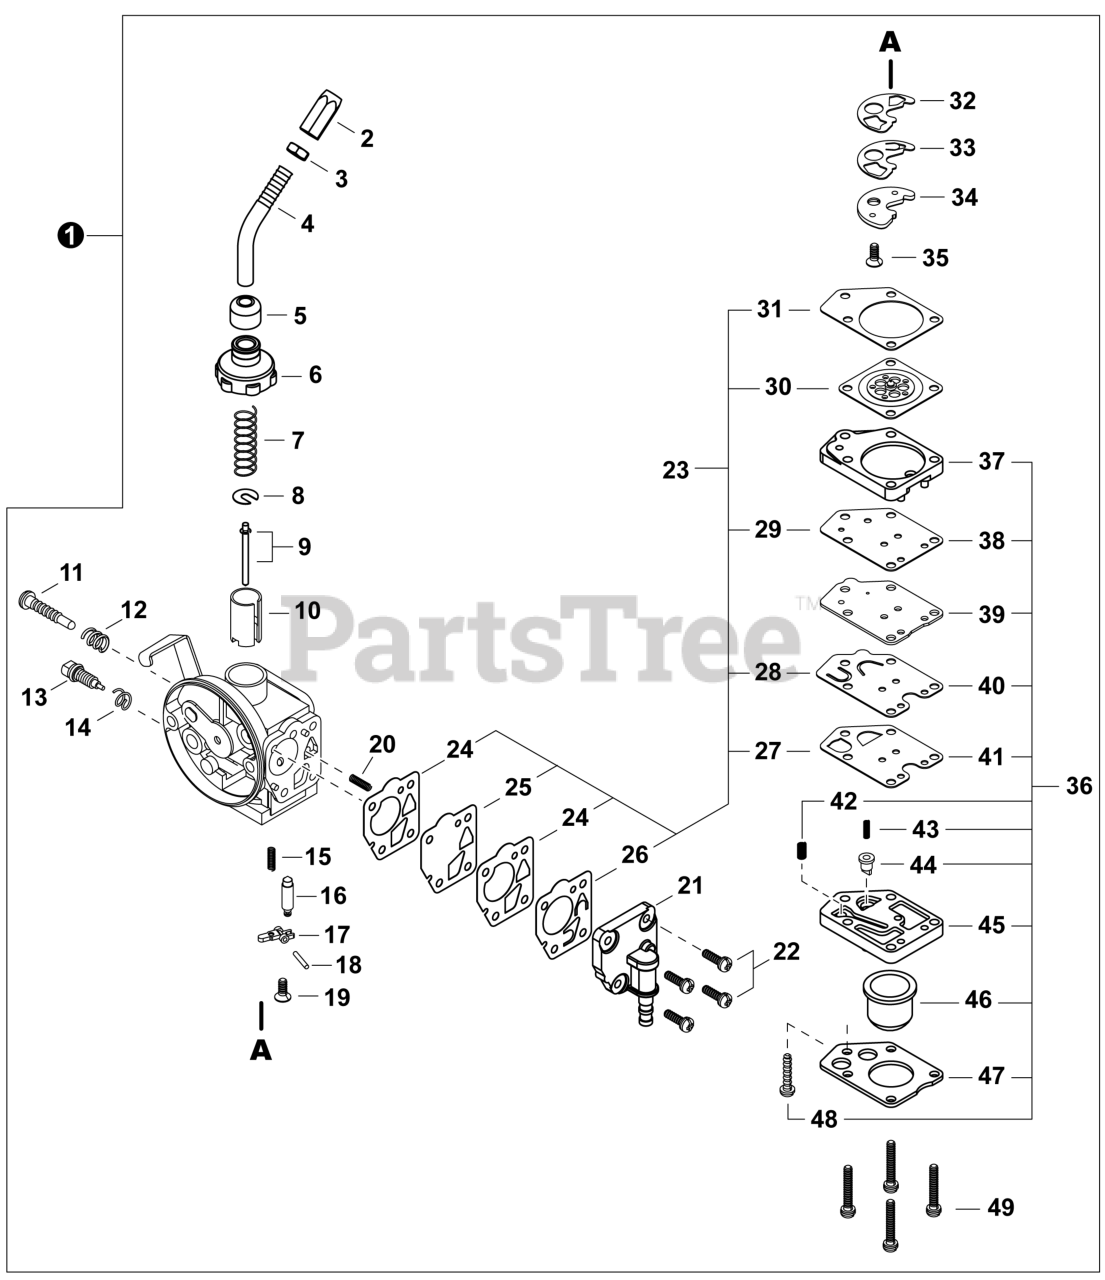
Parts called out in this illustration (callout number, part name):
1	CARBURETOR DPV11W-18B
2	ADJUSTER, CABLE
3	NUT, LOCK
4	PIPE, CABLE ADJUSTER
5	CAP, DUST
6	CAP, CARBURETOR
7	SPRING, THROTTLE
8	WASHER, SPRING SUPPORT
9	NEEDLE, JET
10	VALVE, SLIDE
11	SCREW, IDLE ADJUST
13	SCREW, MAIN ADJUST
16	VALVE, INLET NEEDLE
17	LEVER, METERING
18	PIN, METERING LEVER
19	SCREW M3×8
21	PUMP BODY
23	GASKET / DIAPHRAGM KIT
24	GASKET, DIAPHRAGM
25	DIAPHRAGM, METERING
26	VALVE, PUMP
28	VALVE, CHECK
30	DIAPHRAGM, METERING
31	GASKET, METERING DIAPHRAGM
32	PACKING
33	VALVE, CHECK
35	SCREW M3×8
36	PURGE PUMP KIT
37	COVER, PUMP
39	PLATE, PUMP
40	VALVE, CHECK
44	VALVE, CHECK
45	BODY, PURGE
46	BULB, PURGE
47	RETAINER, PURGE BULB
49	SCREW 3×20
